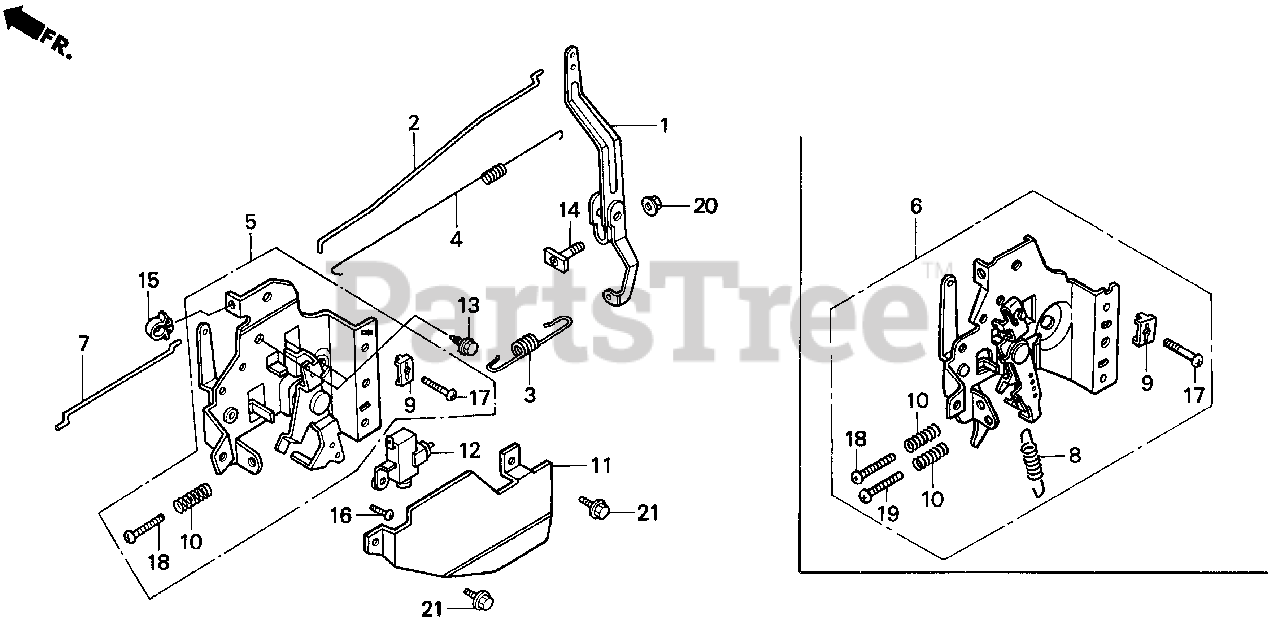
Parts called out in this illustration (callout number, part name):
1	ARM, GOVERNOR
2	ROD, GOVERNOR
3	SPRING, GOVERNOR (STD)
4	SPRING, THROTTLE RETURN
6	CONTROL ASSY.
7	ROD, CHOKE
8	SPRING, LEVER
9	HOLDER, CABLE
10	SPRING, CONTROL ADJUSTING
11	PROTECTOR, CONTROL
12	SWITCH ASSY., ENGINE STOP
13	BOLT, FLANGE (6X12) (CT200)
14	BOLT, GOVERNOR ARM
15	CLIP, WIRE HARNESS
16	SCREW, PAN (4X8)
17	SCREW, PAN (5X16)
18	SCREW, PAN (5X20)
19	SCREW, PAN (5X28)
20	NUT, FLANGE (6MM)
21	BOLT, FLANGE (6X10)
